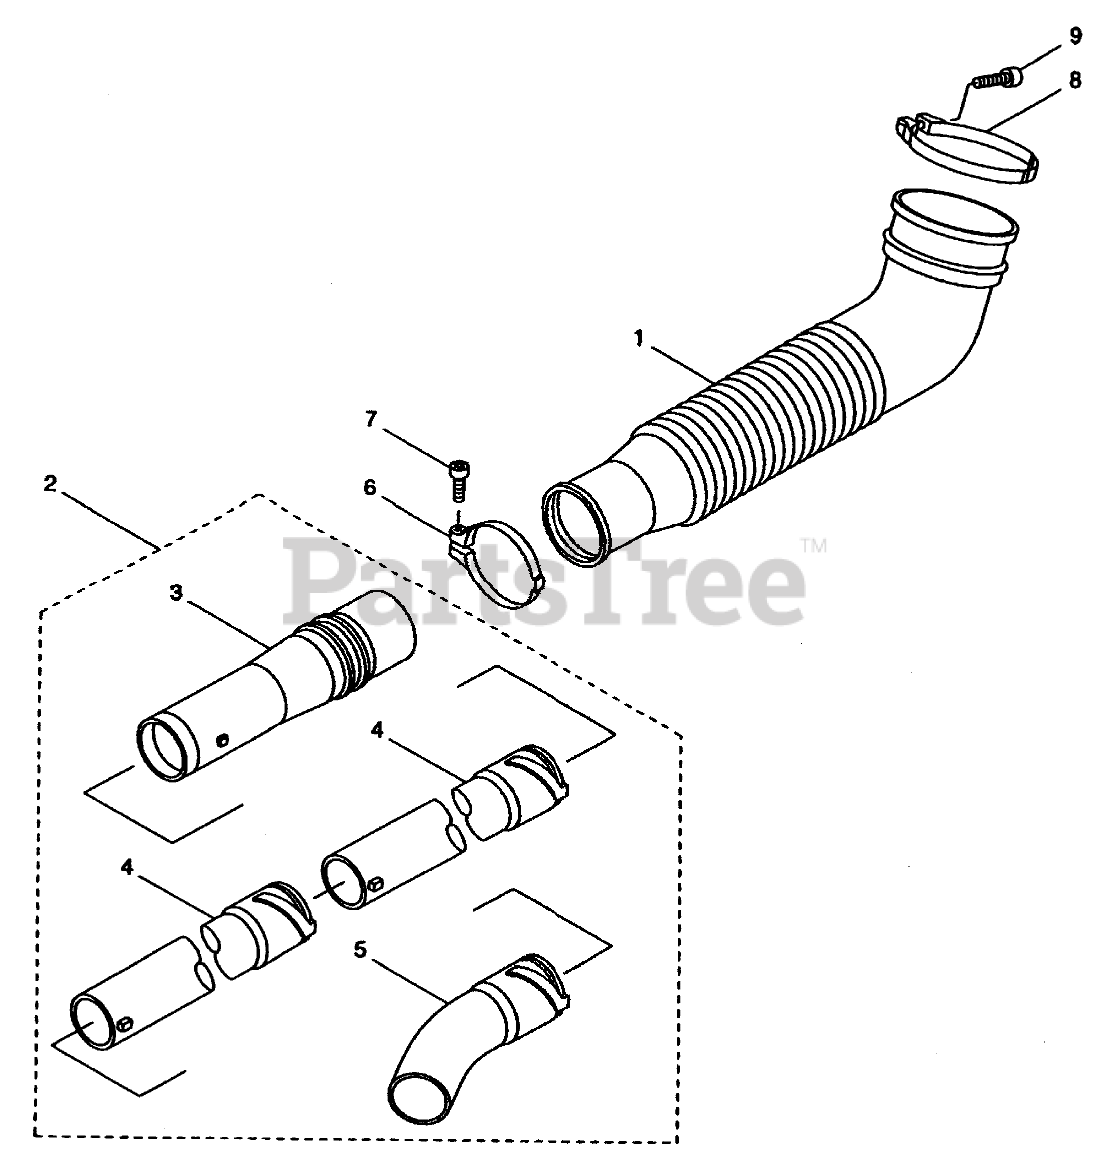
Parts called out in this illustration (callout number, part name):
1	Flexible Pipe
2	Pipe Assembly (Incl, Ref, # 3-5)
3	SWIVEL PIPE ASSY
4	STRAIGHT PIPE
5	BENT PIPE
6	Hose Bend
7	SCREW
8	Hose Band
9	SCREW
